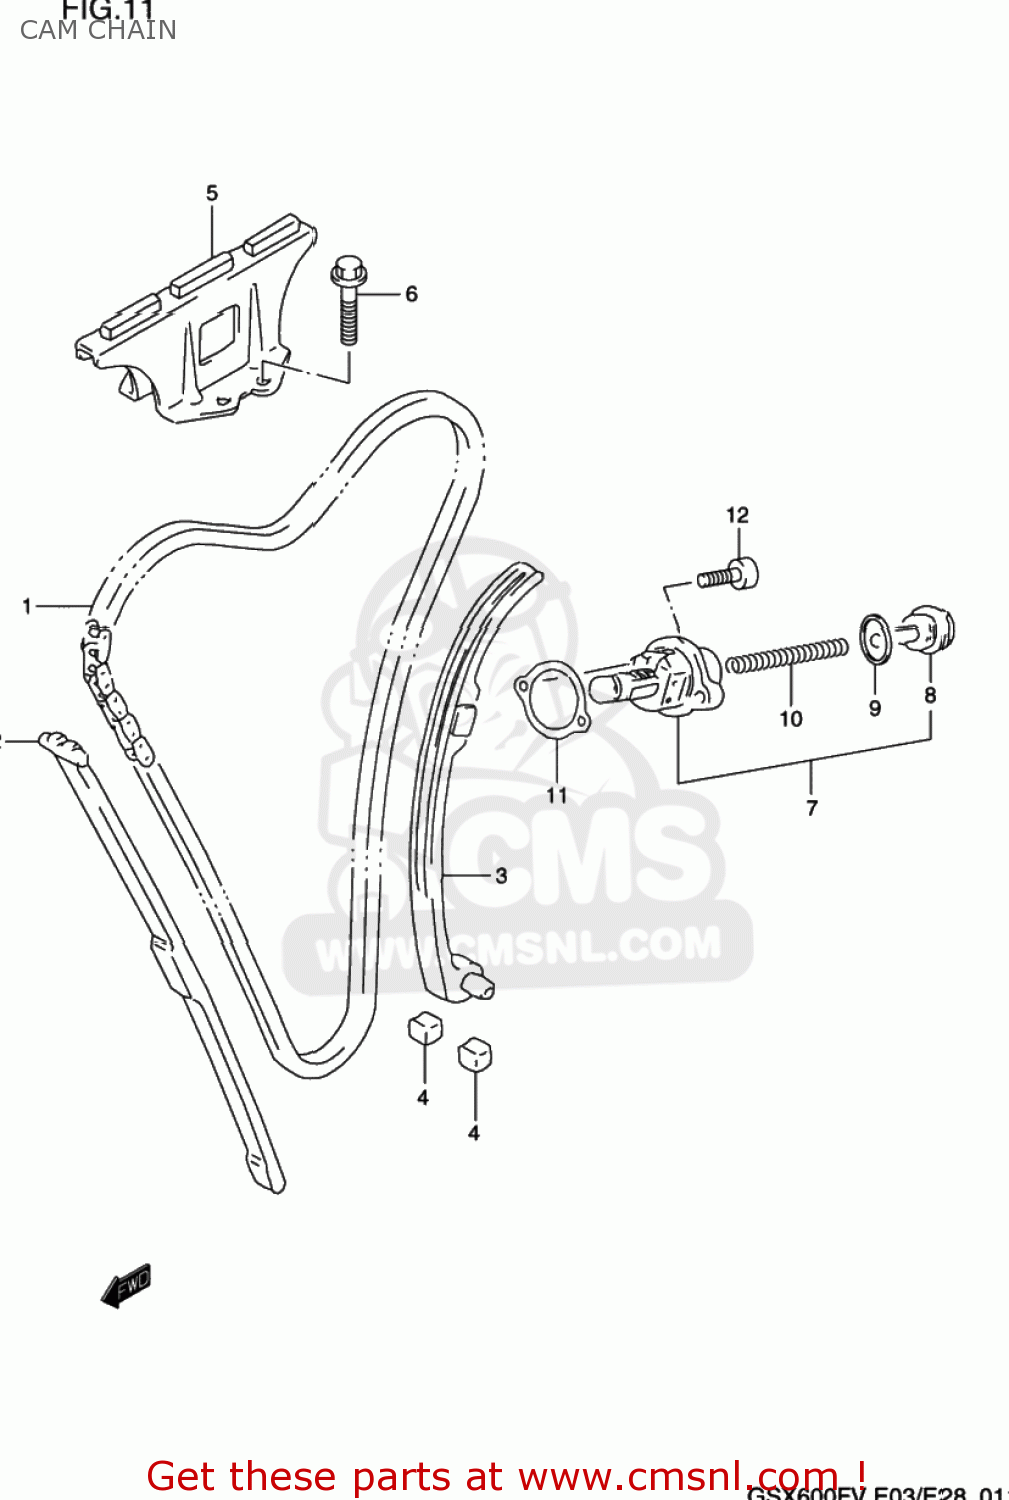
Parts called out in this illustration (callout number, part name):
1	CHAIN,CAMSHAFT DRIVE
2	GUIDE,CAM CHAIN NO.1
3	TENSIONER,CAM CHAIN
4	CUSHION,CAM CHAIN TENSIONER
5	GUIDE,CAM CHAIN NO.2
6	BOLT
7	ADJUSTER ASSY,TENSIONER
8	PLUG
9	GASKET (NAS)
10	SPRING
11	GASKET,TENSIONER ADJUSTER (NAS)
12	BOLT,CL.COVER
